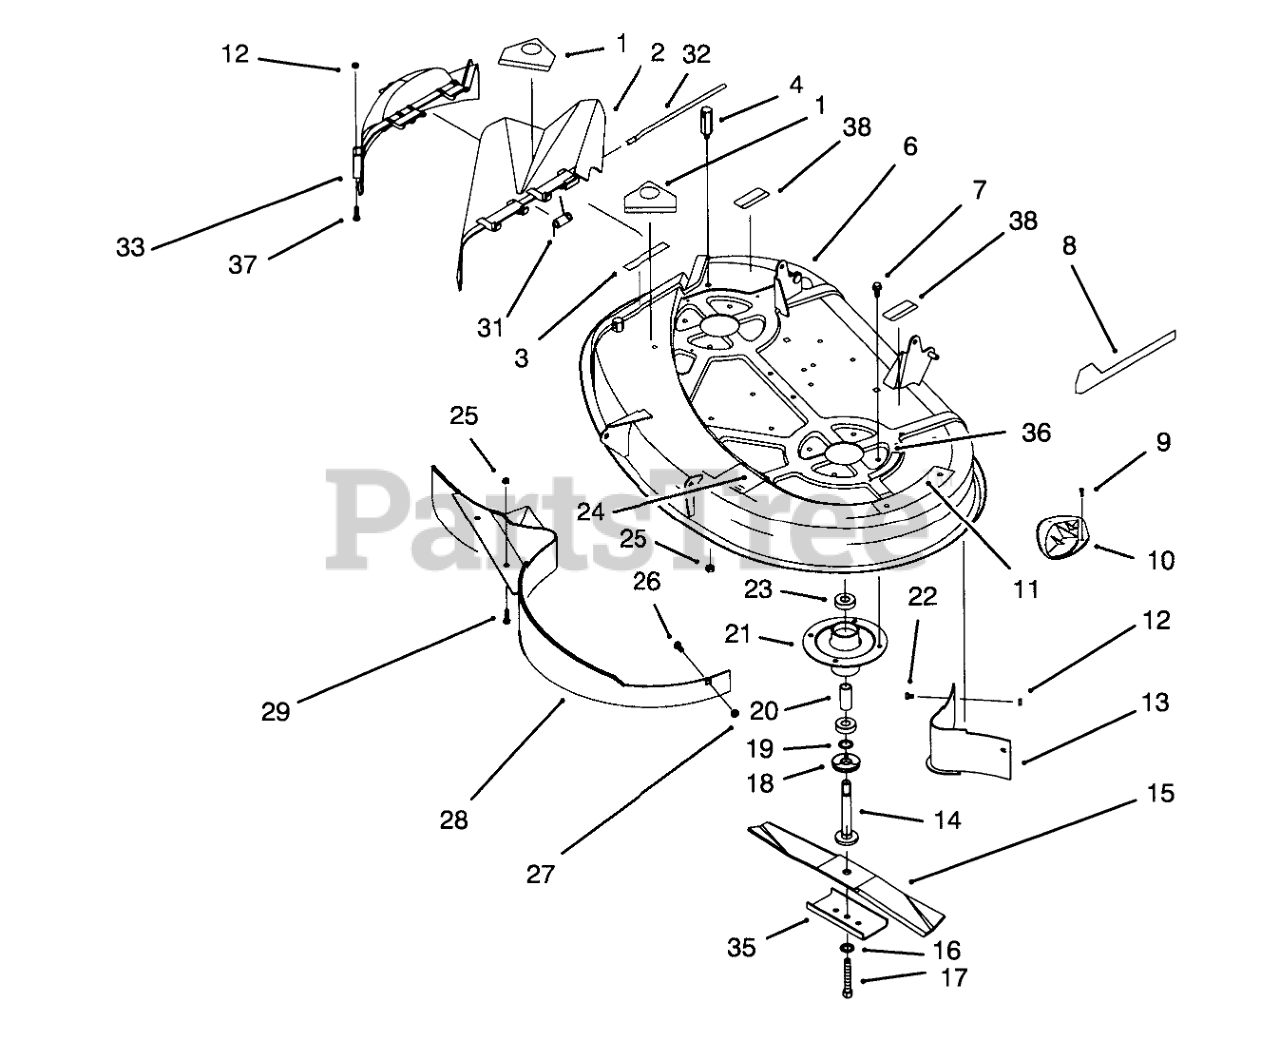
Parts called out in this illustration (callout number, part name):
1	DECAL-DANGER
2	Deflector Assembly (Incl. Ref. #1)
3	DECAL-DANGER, DEFLECTOR
4	REAR PIVOT POST (PLTD)
6	Deck-38"
7	SCREW-TAPTITE
8	DECAL-RECYCLER DECK 38"
9	SCREW-PPH
10	PLATE-KICKER
11	DECAL-DANGER
12	NUT-LOCK, NI
13	Baffle-Rear
14	SHAFT-SPINDLE
15	Blade
16	WASHER-BELLEVILLE
17	SCREW-HH
18	SHIELD-BEARING
19	SPACER
20	SPACER
21	HOUSING-SPINDLE
22	SCREW-HH
23	BEARING-BALL
24	Decal-Routing
25	NUT-LOCK, NI
26	BOLT-CARR
27	NUT-LOCK, NI
28	Baffle-38"
29	SCREW-HH
31	SPRING
32	ROD-HINGE DEFLECTOR
33	COVER-RECYCLER
35	Stiffener
36	DECAL-DANGER, SHIELD
37	SCREW-HH
38	DECAL-WARNING
